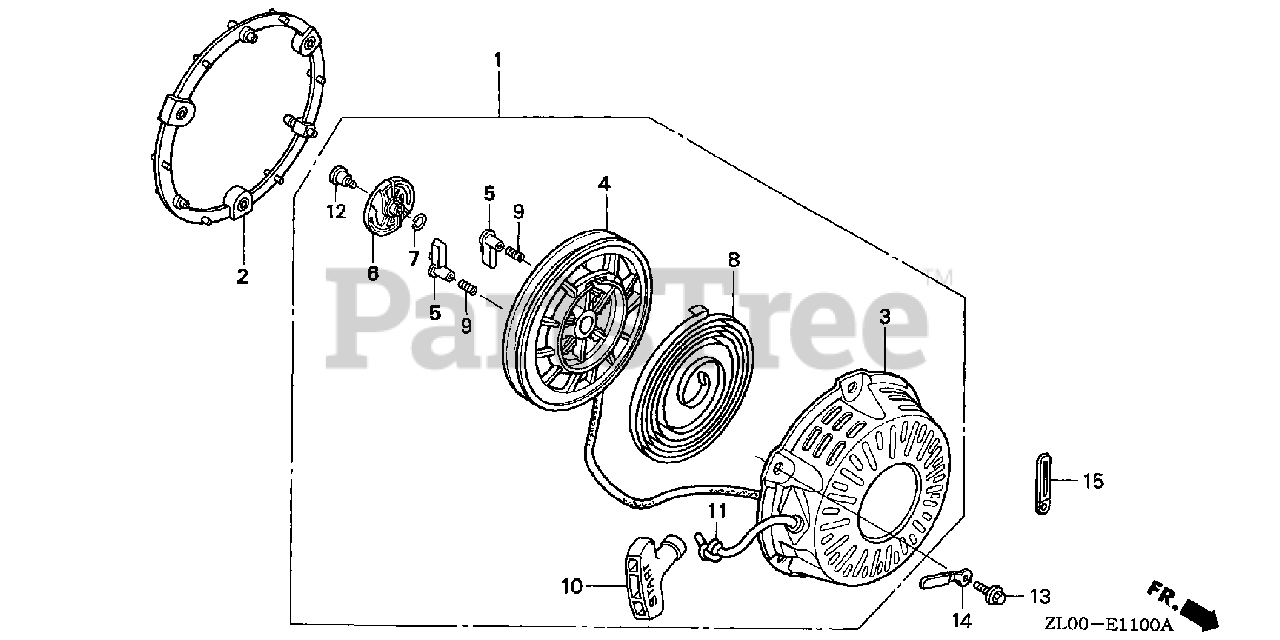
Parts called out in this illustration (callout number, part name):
1	STARTER ASSY., RECOIL *R8* (BRIGHT RED)
2	SPACER, RECOIL STARTER MOUNTING *R8* (BRIGHT RED)
3	CASE, RECOIL STARTER *R8* (BRIGHT RED)
4	REEL, RECOIL STARTER
5	RATCHET, STARTER
6	GUIDE, RATCHET
7	SPRING, FRICTION
8	SPRING, RECOIL STARTER
9	SPRING, RETURN
10	KNOB, RECOIL STARTER
11	ROPE, RECOIL STARTER (NA USE ALT:08550-ZG921-11)
12	SCREW, SETTING
13	BOLT, FLANGE (6X18)
